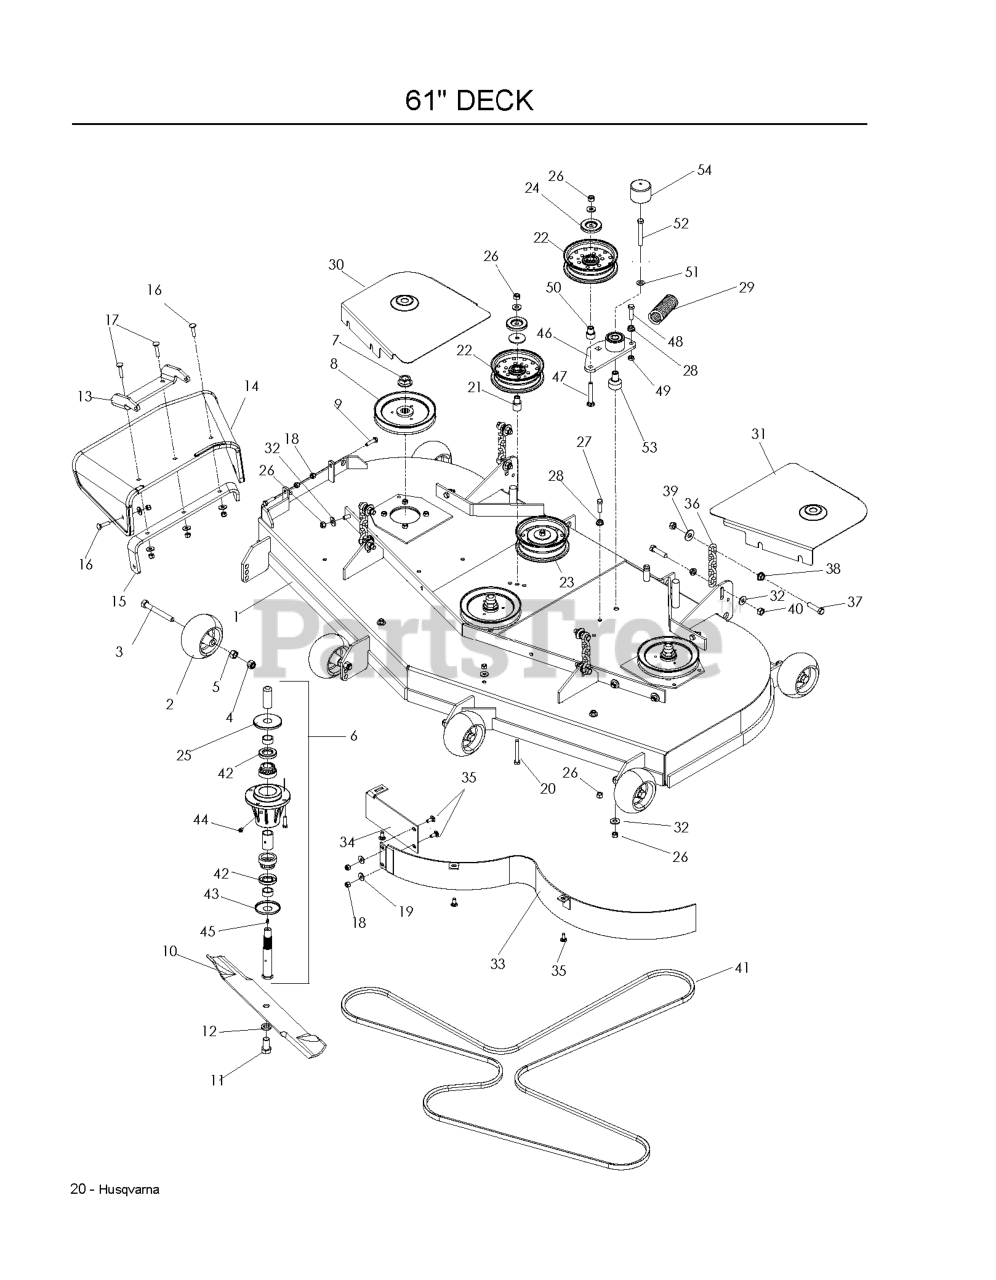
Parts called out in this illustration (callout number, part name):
1	DECK SVC W/DECALS 61" HUS
2	GAUGE WHEEL
3	HCS 1/2-13 X 4 GR 5 ZD
4	NUT 1/2-13 HEX NYLOC ZD
5	NUT HEX 1/2
6	HOUSING ASM, 52/61
7	NUT FLANGE 3/4-16
8	PULLEY, 61
9	HCS 5/16C X 1 1/4
10	BLADE OEM 21" (61" DECK)
11	HCS 5/8F X 1 1/4
12	LOCKWASHER 5/8
13	PIVOT BRACKET - CHUTE
14	CHUTE, RUBBER DISCHARGE 52/61"
15	BRKT, REINF - CHUTE 52/61"
16	BOLT, CARRIAGE 5/16X1-1/4
17	RHSNB 5/16-18 X 1-1/2 GR 5 ZD
18	NUT 5/16 NYLOC
19	WASHER 5/16 FLAT
20	SCREW 3/8C X 2 3/4 HEX CAP
21	IDLER BUSHING
22	IDLER PULLEY
23	IDLER PULLEY (TALL)
24	DUST SHIELD
25	TOP DUST CAP
26	NUT 3/8-16 NYLOC
27	HCS 3/8C X 1 1/4 GR5
28	NUT 3/8C WHIZ
29	DECK SPRING
30	BELT SHIELD 61" RIGHT
31	BELT SHIELD 61" LEFT
32	WASHER 3/8 FLAT
33	MAIN BAFFLE - 61" BLK
34	CENTER BAFFLE - 61
35	BOLT 5/16C X 3/4" CARRIAGE
36	LIFT CHAIN
37	HCS 7/16 - 14 X 1 3/4
38	NUT 7/16C WHIZ
39	WASHER 7/16 FLAT ZD
40	7/16-14 HEX NUT W/NYL RING ZD
41	BELT, DECK 61
42	SHAFT SEAL
43	BOTTOM DUST CAP
44	PLUG-VENTED
45	ZERK
46	ARM-IDLER W/BRG
47	RHSNB 3/8-16 X 2.75
48	HCS 3/8-16 X 1-1/2
49	NUT 3/8-16 HEX JAM
50	BUSHING, IDLER
51	WASHER 3/8 SAE FLAT
52	HCS 3/8C X 3
53	PIVOT, BEARING
54	CAP, VINYL
55	WASHER, 3/8 THICK
